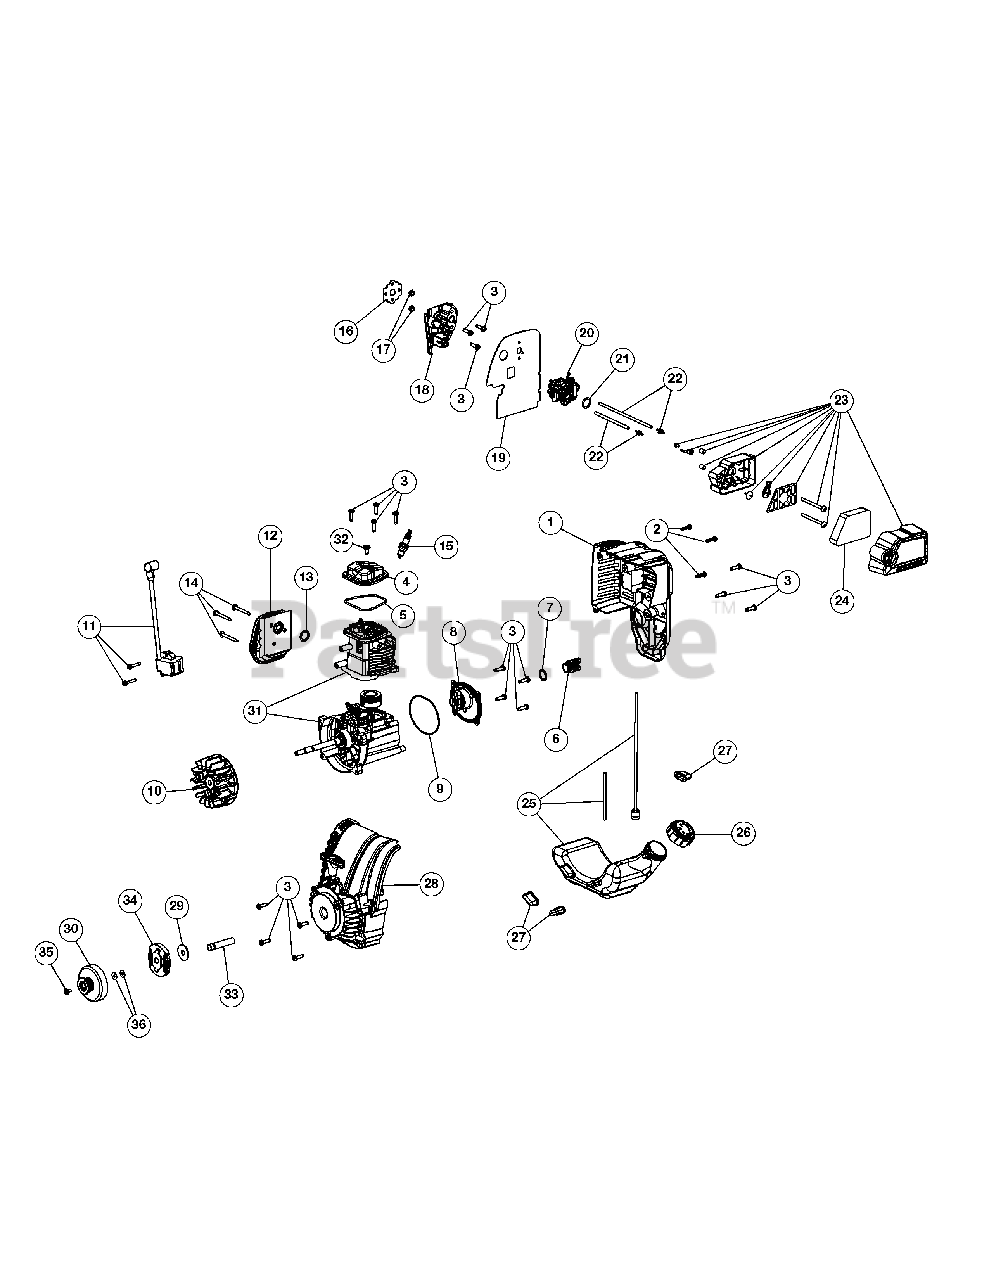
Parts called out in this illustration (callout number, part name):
1	Engine Cover Assembly (Incl. 2 & 3)
2	Cover Screw
3	Starter Screw
4	Rocker Cover
5	Rocker Cover O-Ring
6	Oil Plug (Incl. 7)
7	Oil Plug O-Ring
8	Crankcase Cover
9	Crankcase Cover O-ring
10	Flywheel Assembly
11	Module Assembly
12	Muffler Assembly (Incl. 13 & 14)
13	Muffler Gasket
14	Muffler Screw
15	Spark Plug
16	Insulator Gasket
19	Carburetor Gasket
20	Carburetor w/Primer
23	Air Cleaner Cover Assembly (Incl. 24)
24	Air Filter
25	Fuel Tank Assembly w/Fuel Lines (Incl. 26)
27	Fuel Tank Pads
28	Starter Housing Assembly (Incl. 3)
30	Clutch Drum w/Pulley
31	Shortblock Assembly
34	Clutch (Incl. 29)
36	Washer
